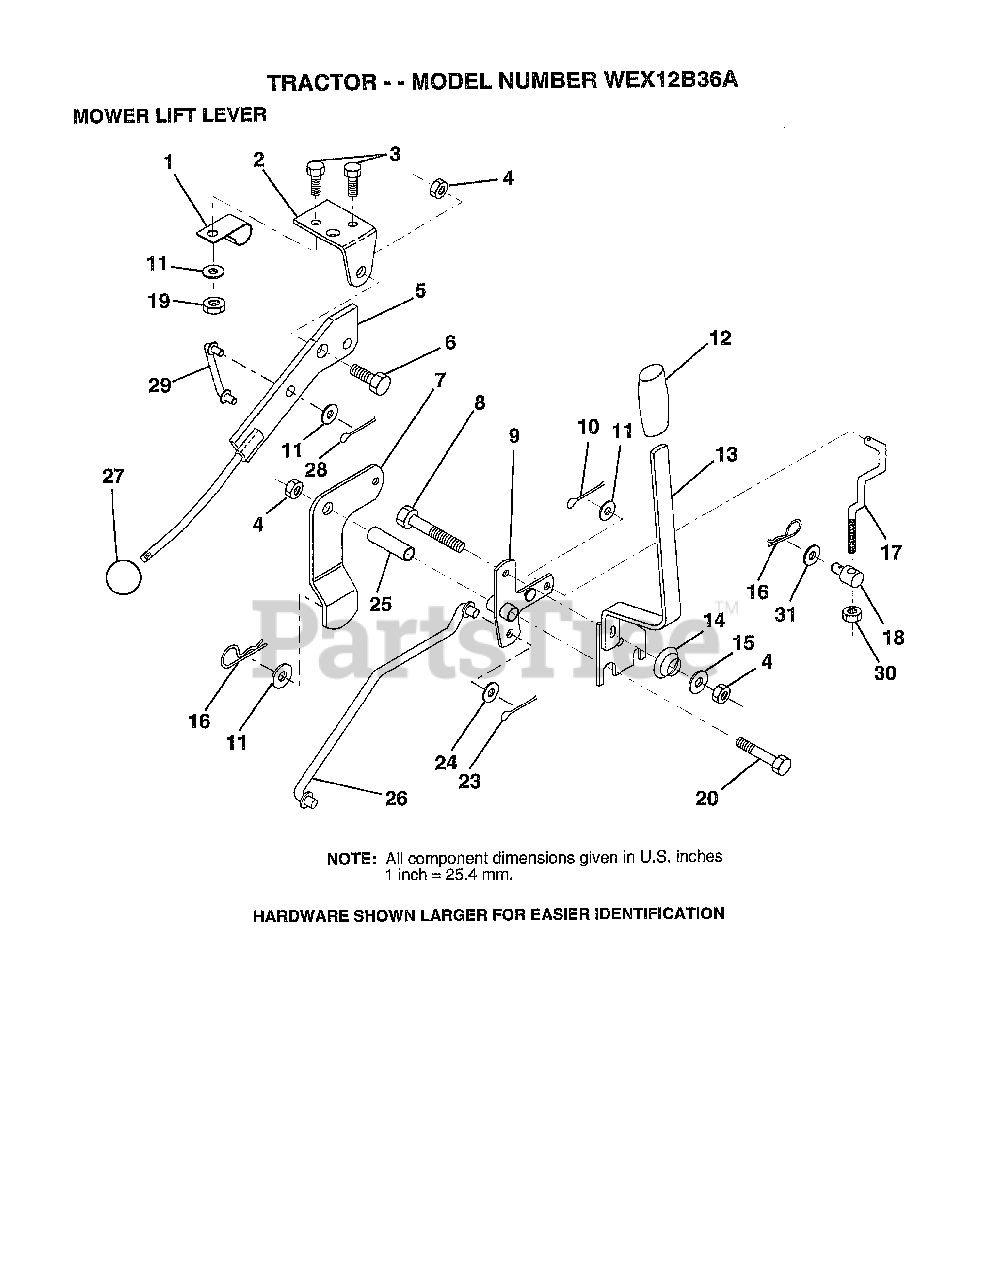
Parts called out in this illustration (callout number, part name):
1	"CLIP,INSULATOR"
2	BRKT CLUTCH
3	BOLT HXHD FIN
5	LEVER.ASM.CLUTCH
6	"BOLT, SHOULDER LT"
7	MWR CLUTCH ARM AS
8	BOLT
9	"BELLCRANK,LIFT"
10	COTTER PIN
11	WASHER
13	HANDLE.ASM.LIFT
14	SPRING COMPRESSIO
15	WASHER T
17	"LINK,LIFT FRT"
18	TRUNION ADJ
19	NUT HXKEP 1/4X20
20	BOLT
23	PIN COTTER 1/8
25	TUBE SPACER
26	ROD LIFT MOWER
27	KNOB T(3/8 HOLE)
29	CLUTCH LINK
30	NUT
31	WASHER
